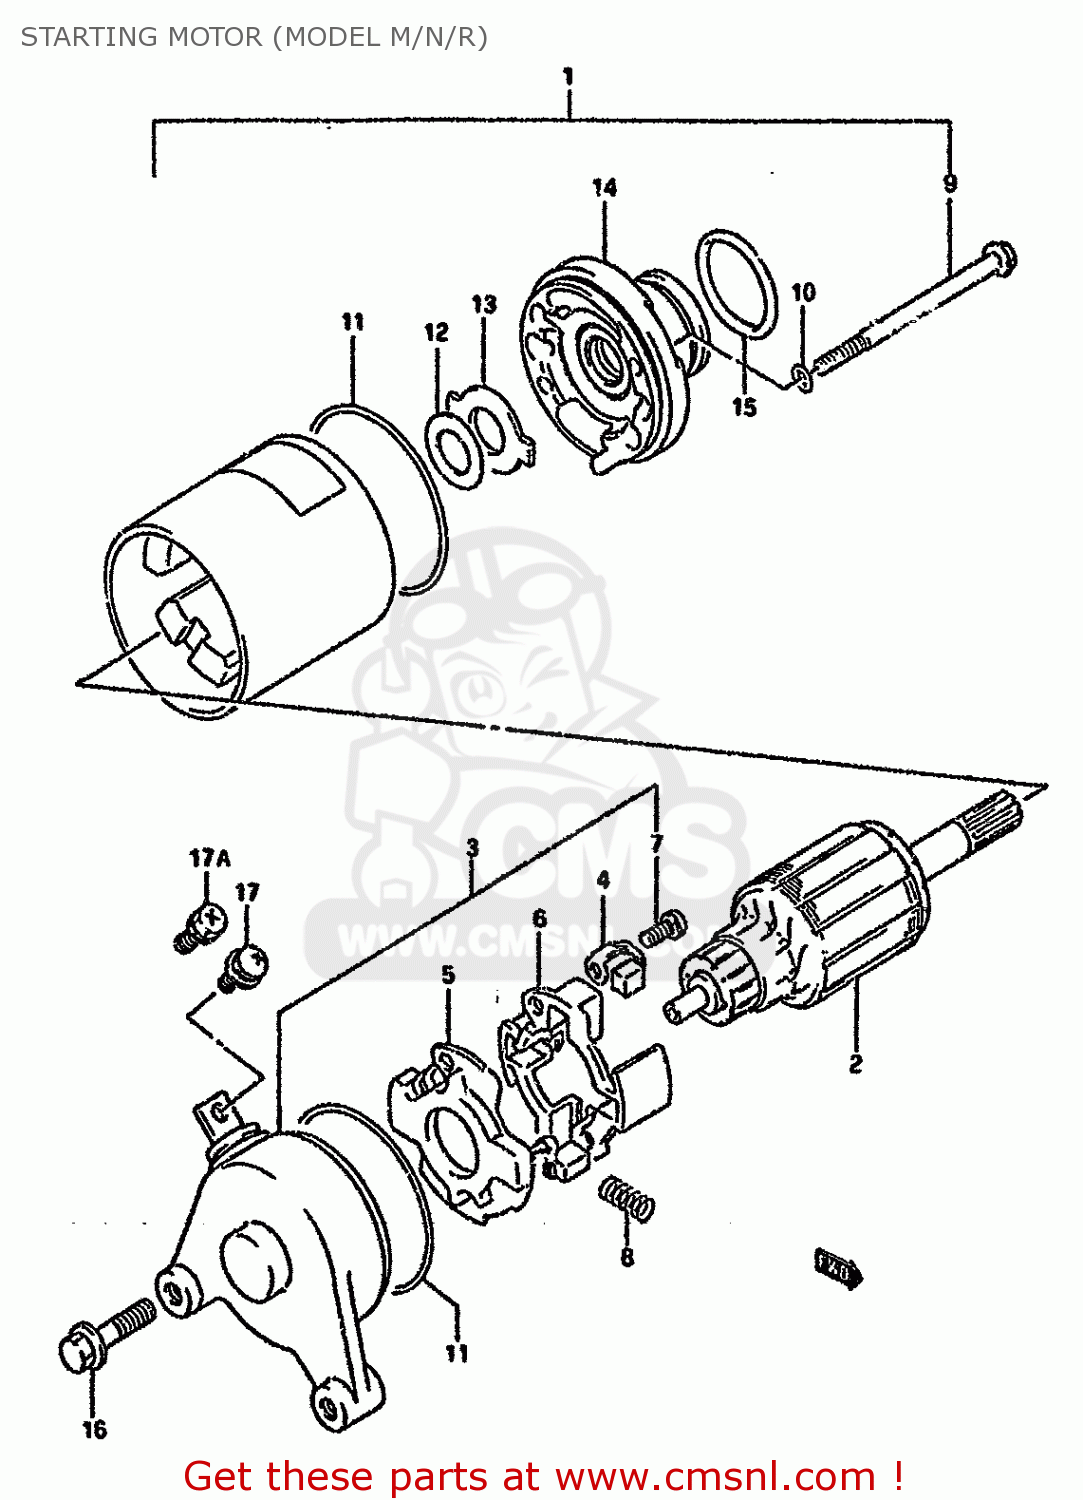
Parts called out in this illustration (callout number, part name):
1	MOTOR ASSEMBLY,STARTING
2	ARMATURE
3	FRAME ASSEMBLY,COMMUTATOR
4	BRUSH
5	BRUSH SUB ASSY,STARTER
6	HOLDER,BRUSH
7	SCREW
8	SPRING
9	BOLT
10	O RING
11	O RING
12	SHIM
13	PLATE,LOCK
14	BRACKET
15	O RING(D:3,ID:24.5)
16	BOLT
17	SCREW
17A	SCREW(5X8)
21	WASHER,LOCK
22	WASHER (6.7X16X1.8)
23	O RING(D:3,ID:24.5)
24	BOLT
